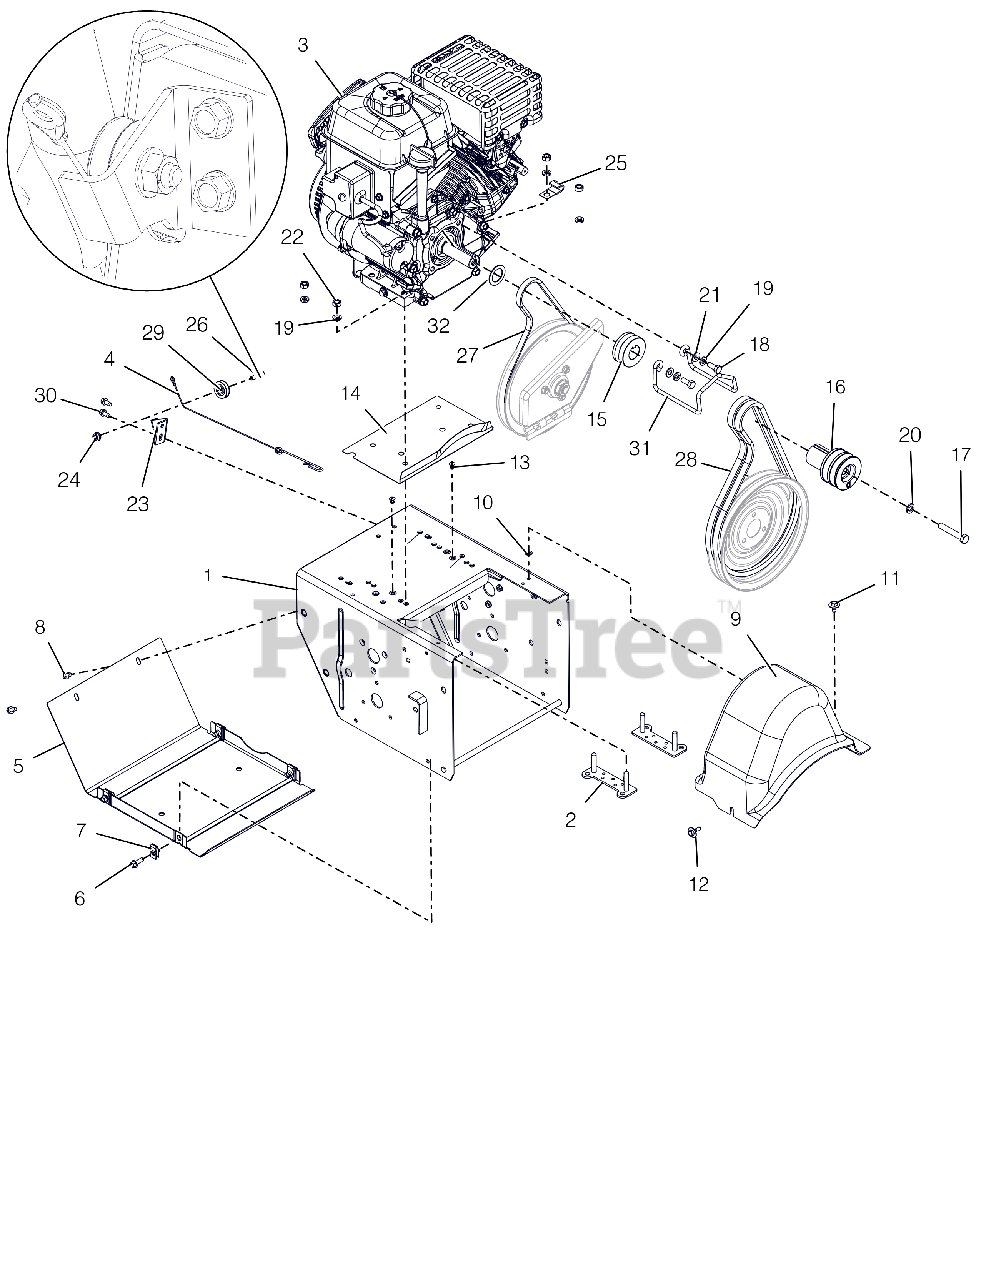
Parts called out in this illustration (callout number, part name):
1	FRAME, MAIN-DELUXE(WELDMENT)
2	STRAP, BOLT - SMALL ENGINE
3	ENGINE, AX254 GEN2 120V/60W
4	CABLE, LOWER TRACTION,SS & PRO
5	COVER, BOTTOM
6	BLT-HEX .25-20X.75 HWH YZ GR5
7	NUT-RTNR .25-20X.56
8	SCR-TAP .25-20X.50 HWH TR YWZ
9	COVER, BELT-SMALL
10	NUT-PUSH .25X.50 O.D.
11	SCR-TAP .25-20X.50 LGHWH TR YZ
12	SCR-TAP .25-20X.5 CAPTIVE
13	RVT-POP .187 YZ
14	BAFFLE, WATER-SMALL
15	SHEAVE, DRIVE
16	SHEAVE,ATTACHMENT-STD 2 GRV
17	BLT-HEX .38-24X2.25 YWZC GR5
18	BLT-HEX .31-24X.75 YWZC GR5
19	WSHR-LK .312X.097 HVY YWZC
20	@WSHR-LK .38X.094 REG YWZC
21	@WSHR-FL-STL.344X.688X.065YWZC
22	@NUT-HEX .31-18 YWZC
23	BRACKET, CABLE PULLEY
24	@NUT-LK-TOP-FLG .25-20 YWZC
25	J-CLAMP
26	BOLT, SHLDR-.375X.375X.25-20
27	V-BELT, 3L-WRAPPED
28	V-BELT, HA-RAW EDGE (SET)
29	PULLEY, CABLE
30	SCR-TAP .25-20X.50 HWH TR YWZ
31	FINGER, BELT
32	WSHR-FL-STL 1.010X1.505X.062YZ
